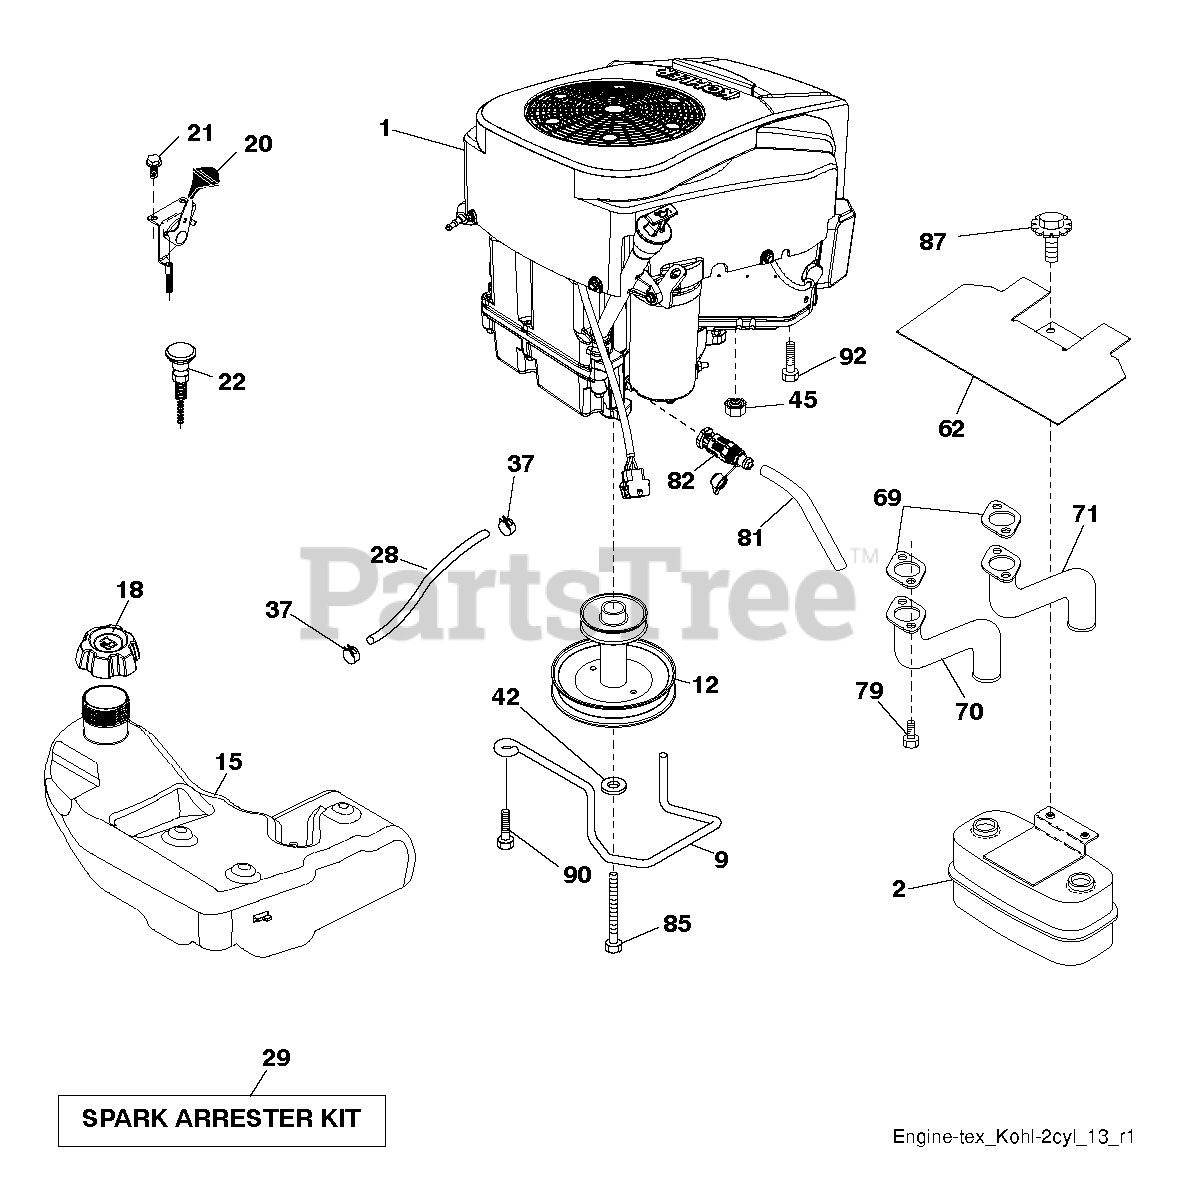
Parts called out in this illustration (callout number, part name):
2	MUFFLER.ASM.TWN.EXTNDED.DFLCTR
9	KEEPER.BELT.ENGINE.4.2
12	PULLEY ENGINE
15	TANK.ASSY.3.GAL.EPA
18	CAP.ASM.FL.RITCH.3"E10.SYM.498
20	THROTTLE CONTROL
21	SCREW.#10 X 0.750.BOS
22	CONTROL.CHOKE.ERGO.PUSH-IN.BLA
28	LINE.FUEL.20
29	KIT.SPARK ARRESTOR 794945 B&S
37	HOSE CLAMP
42	LOCKWASHER
45	NUT
62	SHIELD.HEAT.MUFFLER
69	GASKET.EXHAUST.KOHL.CV18-CV26
70	RP.PIPE-EXHAUST LH
71	RP.PIPE-EXHAUST RH
79	SCREW.SOCKET HD.5/16-1
81	TUBE, DRAIN OIL ASM.
82	VALUE.OIL.DRAIN
85	BOLT HEX 7/16-20X4-1/4"
87	Bolt, 5/16-18 X 1-3/4
90	SCREW 3/8-16X1
92	SCREW 3/8-16X1
